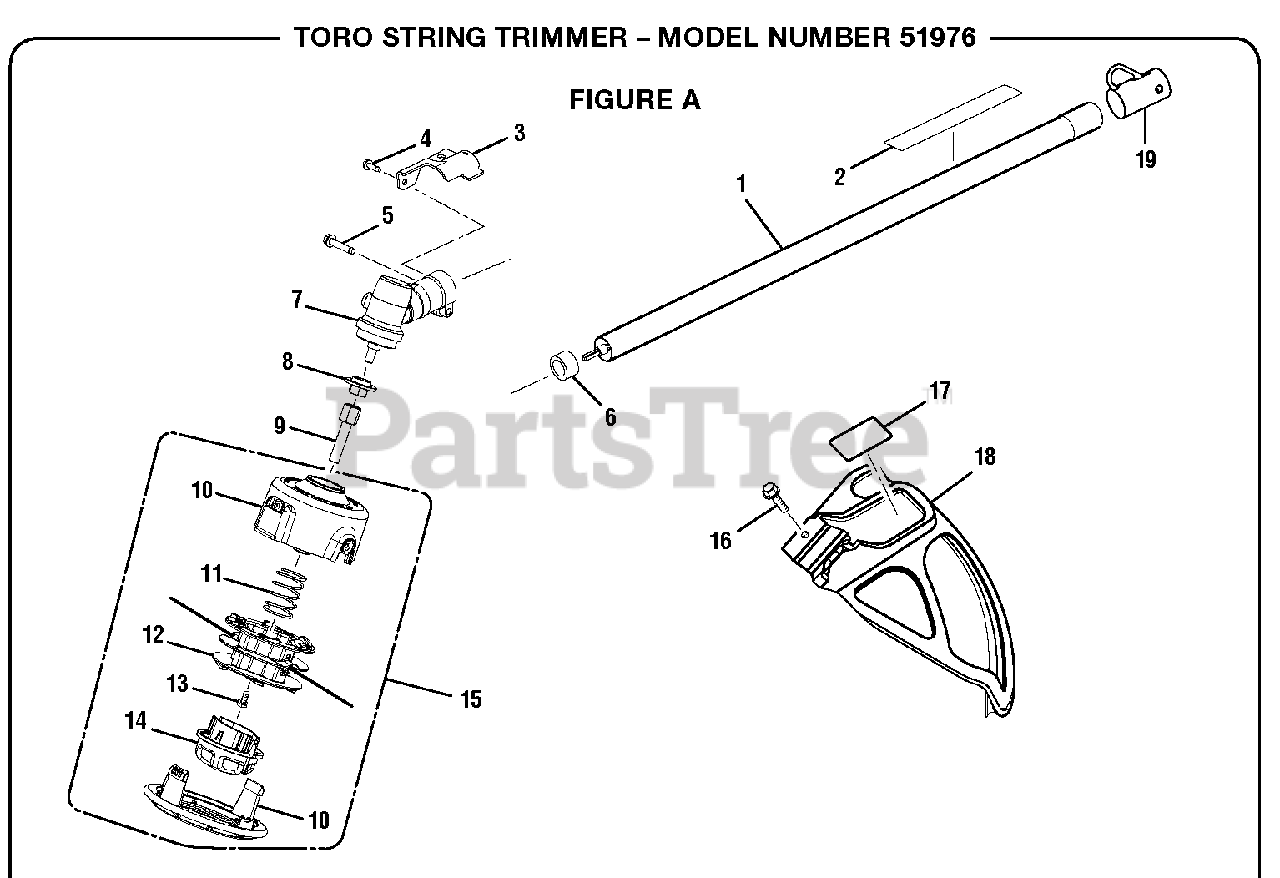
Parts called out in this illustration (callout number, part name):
1	Straight Shaft Assembly
2	Warning Label
3	Grass Deflector Clamp
4	Screw (#10-24 x 5/8 in. Hex Washer Hd.)
5	Screw (1/4-20 x 1-1/4 in.)
7	Gear Case Assembly
8	Flanged Washer
9	Trimmer Head Shaft Adaptor
10	Stringhead Housing
11	Compression Spring
12	Spool
13	Bolt (5/16-18 x 1/2 in., L.H.)
14	Bump Knob
15	Trimmer Head Assembly
16	Screw (#1/4-20 x 1-1/4 in. Hex Washer Hd.)
17	Grass Deflector Label
18	Grass Deflector Assembly
19	Hanger Cap
